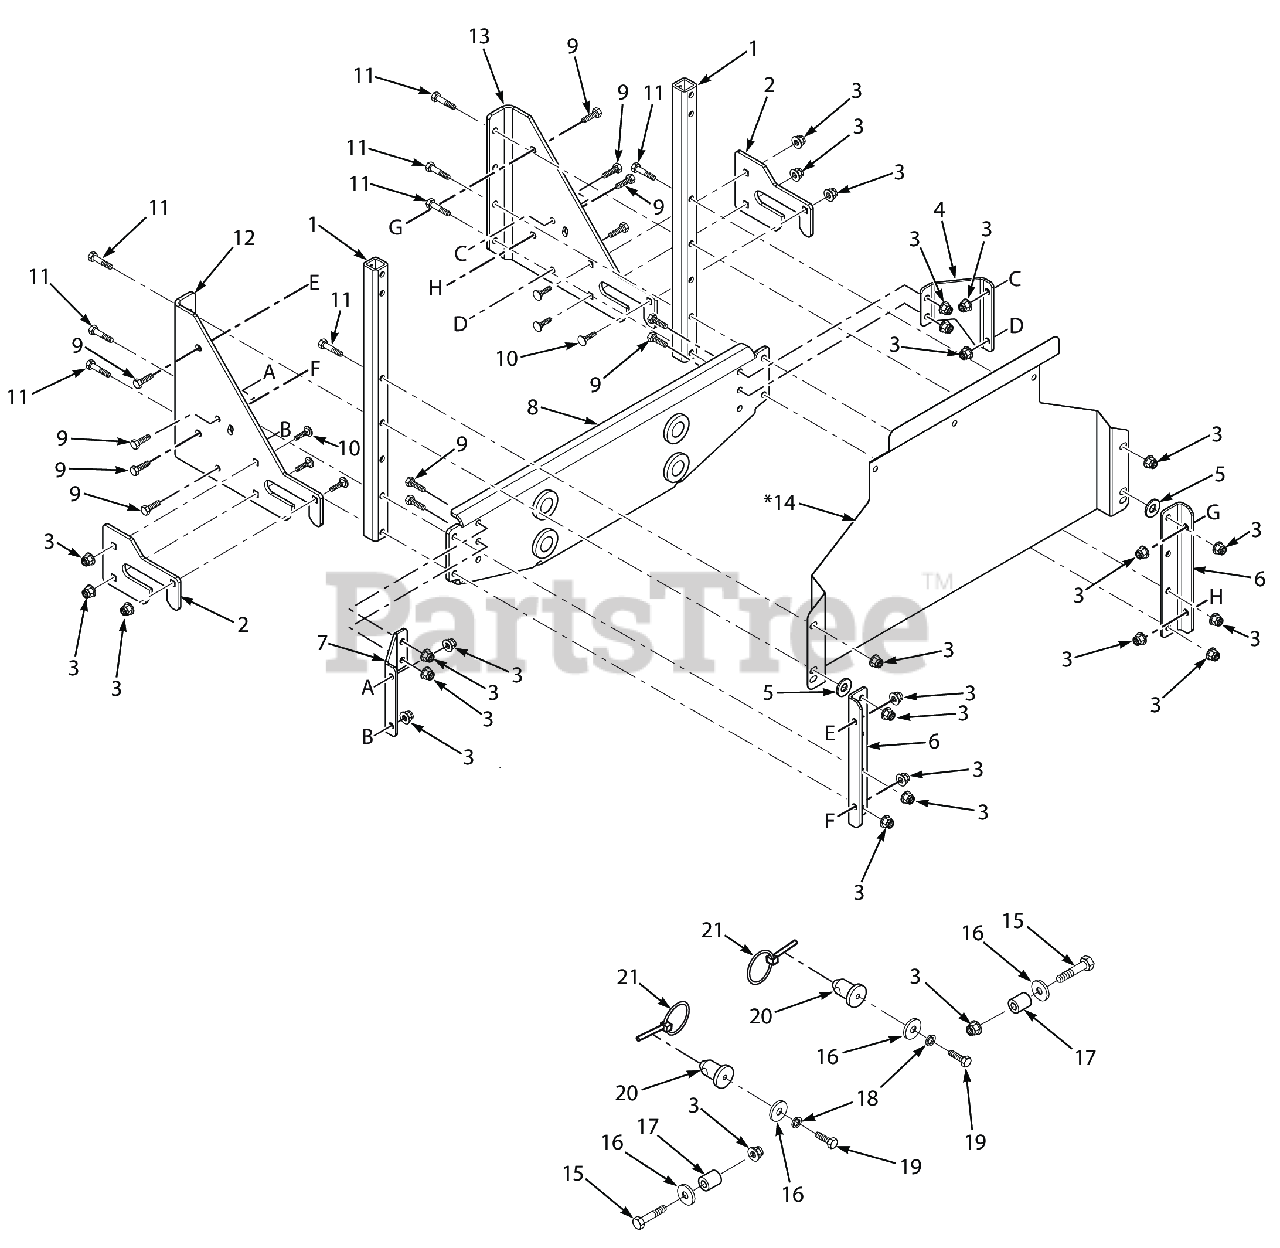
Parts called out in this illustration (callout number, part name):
1	Tube, Upright
2	Wear Plate, GC
3	Nut, Flange Elastic Stop Nut, 3/8-16
4	Angle Brace, LH GC
5	Flatwasher, 7/16-.469 x 1.75 x .25 (48, 52)
6	Mounting Bracket, GC Tube
7	Angle Brace, RH GC
8	Mounting Bracket Weldment
9	Bolt, Hex Head 3/8-16 x 1"
10	Carriage Bolt, 3/8-16 x 1.0"
11	Capscrew, Hex Head 3/8-16 x 2-1/2"
12	RH Mounting Bracket, GC
13	LH Mounting Bracket, GC
14	Heatshield (used on STT & STTII Models Only)
15	Bolt, Hex Head 3/8-16 x 2-1/4"
16	Flatwasher, 3/8-.406 x 1-1-1/2 x 7 Gauge
17	Spacer
18	Lockwasher, 3/8" Spring, Kawasaki FX / FS
19	Bolt, Hex Head 3/8-16 x 1-1/4", Kawasaki FX / FS
20	Pin, GC Locator
21	Quick Pin, 5/16" Dia.
